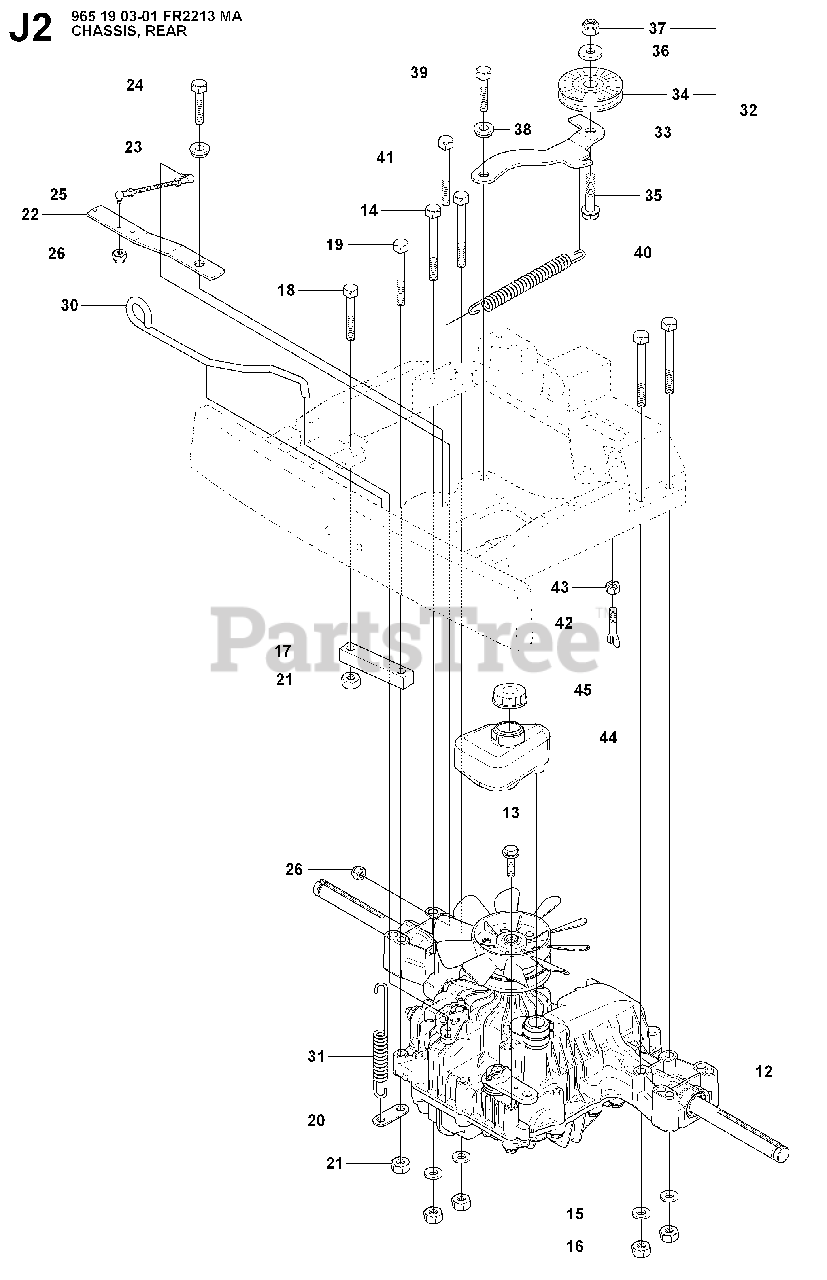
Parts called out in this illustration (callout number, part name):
12	HYDROSTAT
15	WASHER BRB 8.4X17
16	NUT
20	CONNECTOR
21	NUT
23	WASHER
24	SCREW 8X20
26	LOCKNUT M5
31	SPRING
32	TENSIONER
33	TENSIONER
37	LOCKNUT M8
38	WASHER
39	SCREW 8X20
